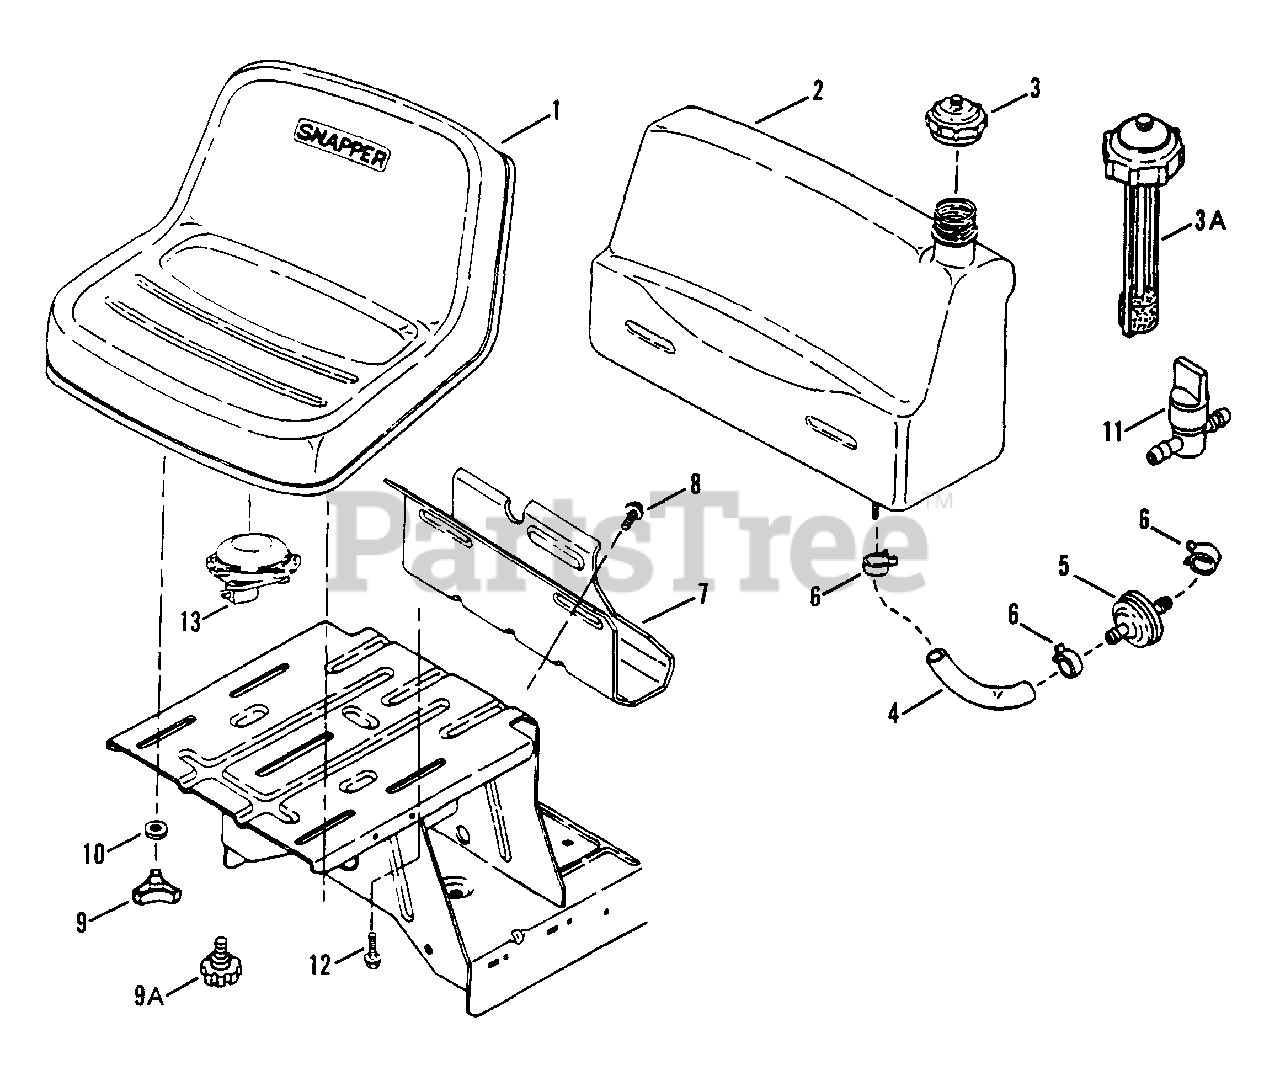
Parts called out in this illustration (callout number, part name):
1	SEAT, Operator
2	ASSEMBLY, Fuel Tank
3	CAP, Fuel Tank w/gauge
3A	CAP, Fuel Tank With Gauge
4	HOSE, Fuel (7" Long)
5	FILTER, Fuel (In-Line)
6	CLAMP, Fuel Line
7	BRACKET, Fuel Tank (Rear)
8	SCREW, 5/16-18 x 5/8" Self-Tapping
9	KNOB, Seat Adjusting (25" & 28 Models)
9A	KNOB, Hinged Seat
10	SPACER, 5/16 (33" Models)
11	VALVE, Fuel Shut-Off (Accessory)
12	BOLT, 5/16-18 x 1/2" Hex Flange Lock
13	SWITCH, Seat (25" & 28" Models)
